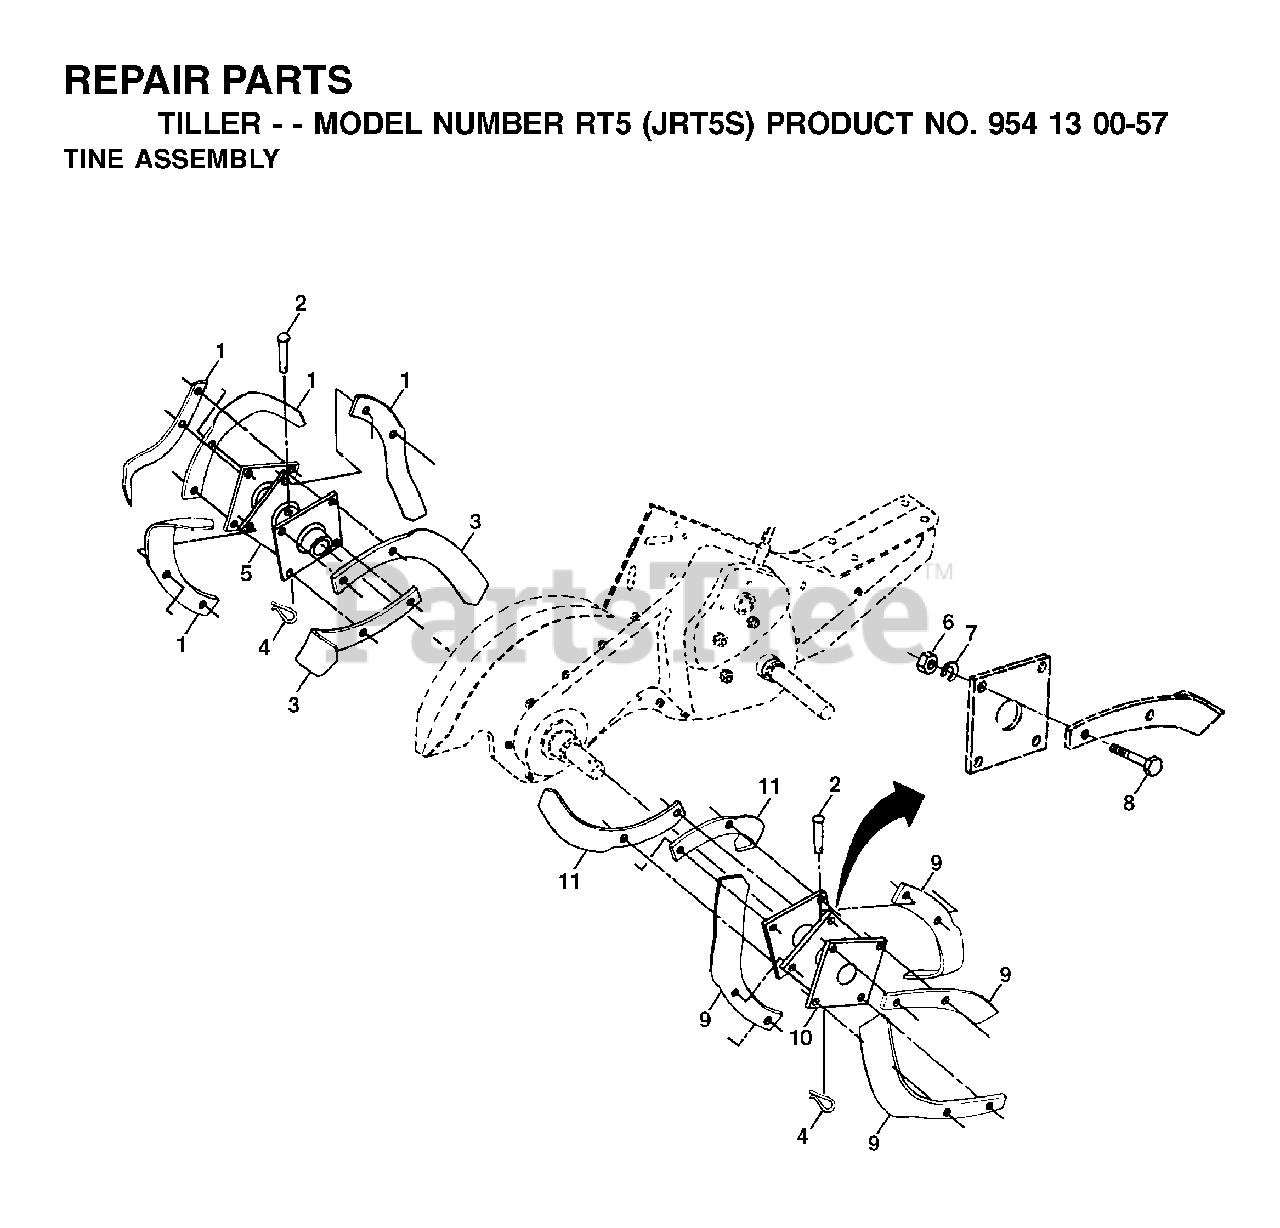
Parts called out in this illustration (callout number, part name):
1	TINE TI
2	CLEVIS PIN
3	TINE.LH.12"
4	SPRING RETAINER
5	HUB & PLATE ASM LH
6	NUT
7	WASHER, LOCK 3/8
8	BOLT.HEX.001X20.37-24X1.ZINC
9	TINE TI
10	HUB & PLATE ASM RH
11	TINE.RH.12"(72R)
